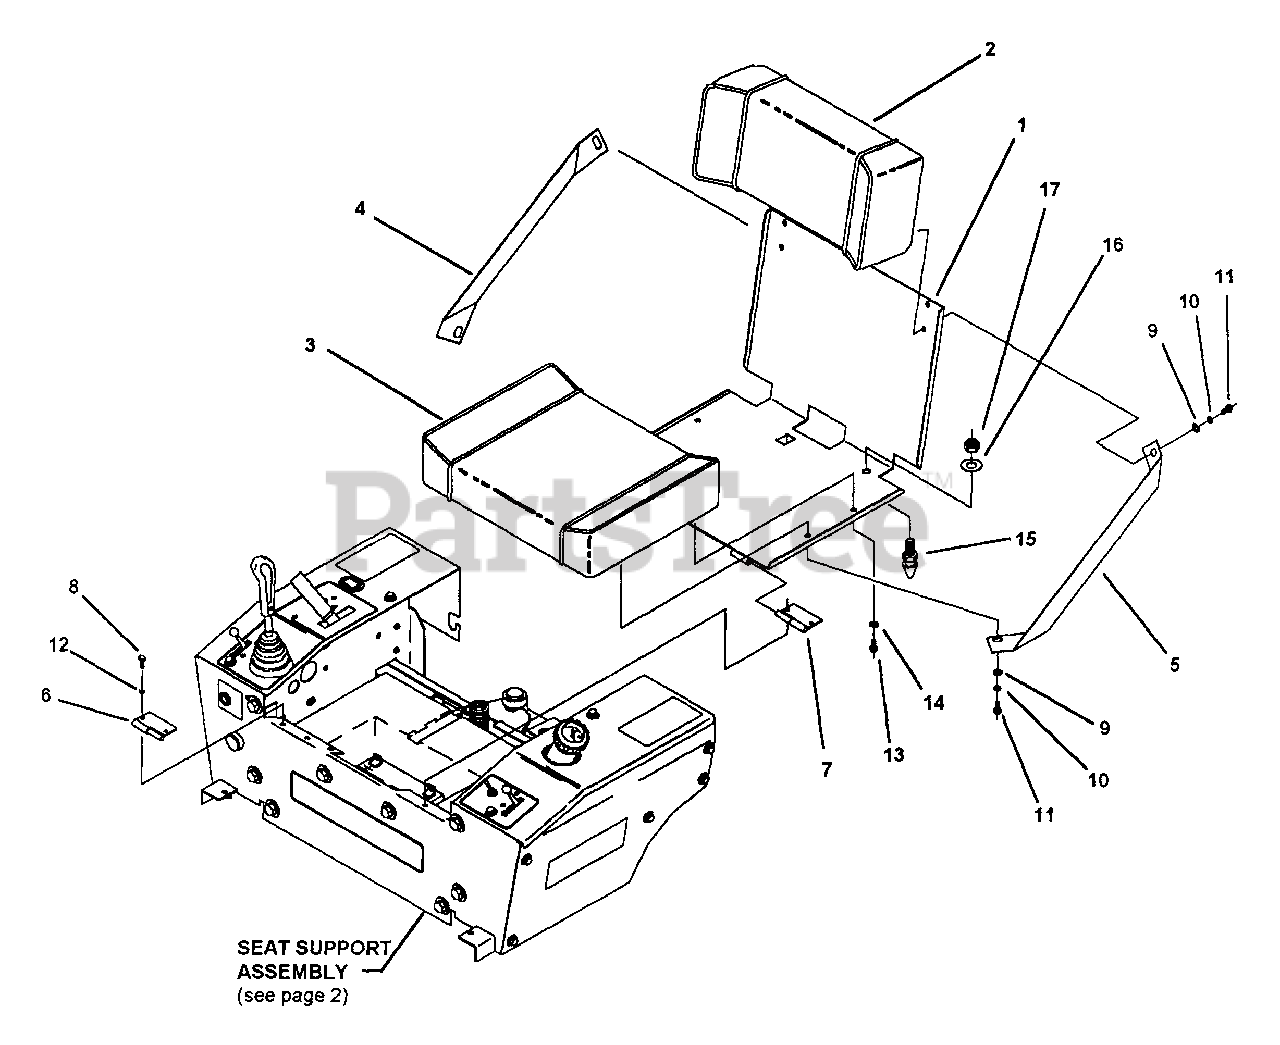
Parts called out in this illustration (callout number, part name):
1	SEAT BRACKET WLDT.
1	MOWER DECK
2	CUSHION BACK ASSEMBLY
3	CUSHION SEAT ASSEMBLY
4	GUSSET, SEAT RIGHT
5	GUSSET, SEAT LEFT
6	HINGE
8	BOLT, 1/4-20 X 3/4" GR. 5
9	WASHER, 5/16" SAE
10	LOCKWASHER, 5/16" SPLIT SPRING
11	BOLT, 5/16-18 X 1" GR. 5
12	LOCKWASHER, 1/4" SPLIT SPRING
13	BOLT, 5/16-18 X 5/8" LONG LOCK
14	WASHER, 5/16 ID X 5/8 OD X .035 THK
15	LATCH PIN
16	WASHER, FLAT STD. 1/2"
17	1/2-13 LOCKNUT W/NYLOC
